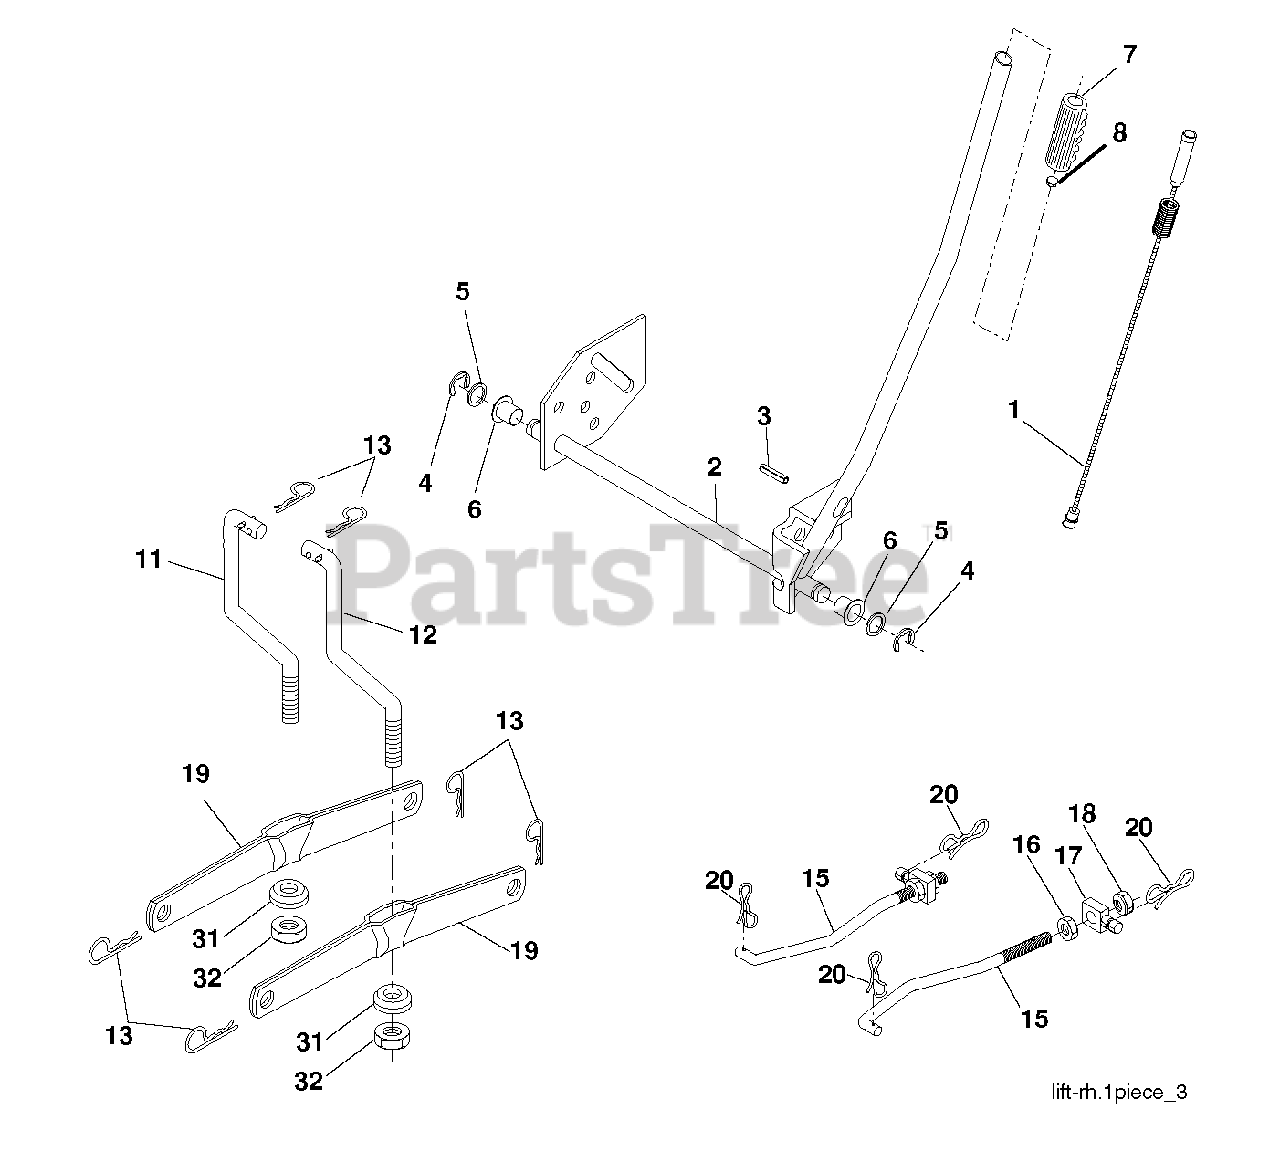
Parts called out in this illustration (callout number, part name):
1	PLUNGER.ASM.LIFT.LEVER.BLK.
2	SHAFT.ASM.LIFT.YT
3	PIN.GROOVE.5/16
4	RETAINING RING LT
6	BEARING.NYLON
7	GRIP
8	PLUNGER BUT KIT
11	LINK LIFT LH
12	Lift Link Assembly, RH
13	RETAINER-SPRNG RB
15	LINK.SUSPENSION.FRONT
16	NUT.HEX.JAM.1/2-13
17	TRUNNION
18	NUT.LK.W/WSH.1/2.
19	ARM.REAR.SUSPENSION
20	PIN.COTTER.7/16.BOW TI.
31	BEARING.PIVOT.LIFT
32	NUT CROWNLOCK 3/8-24
